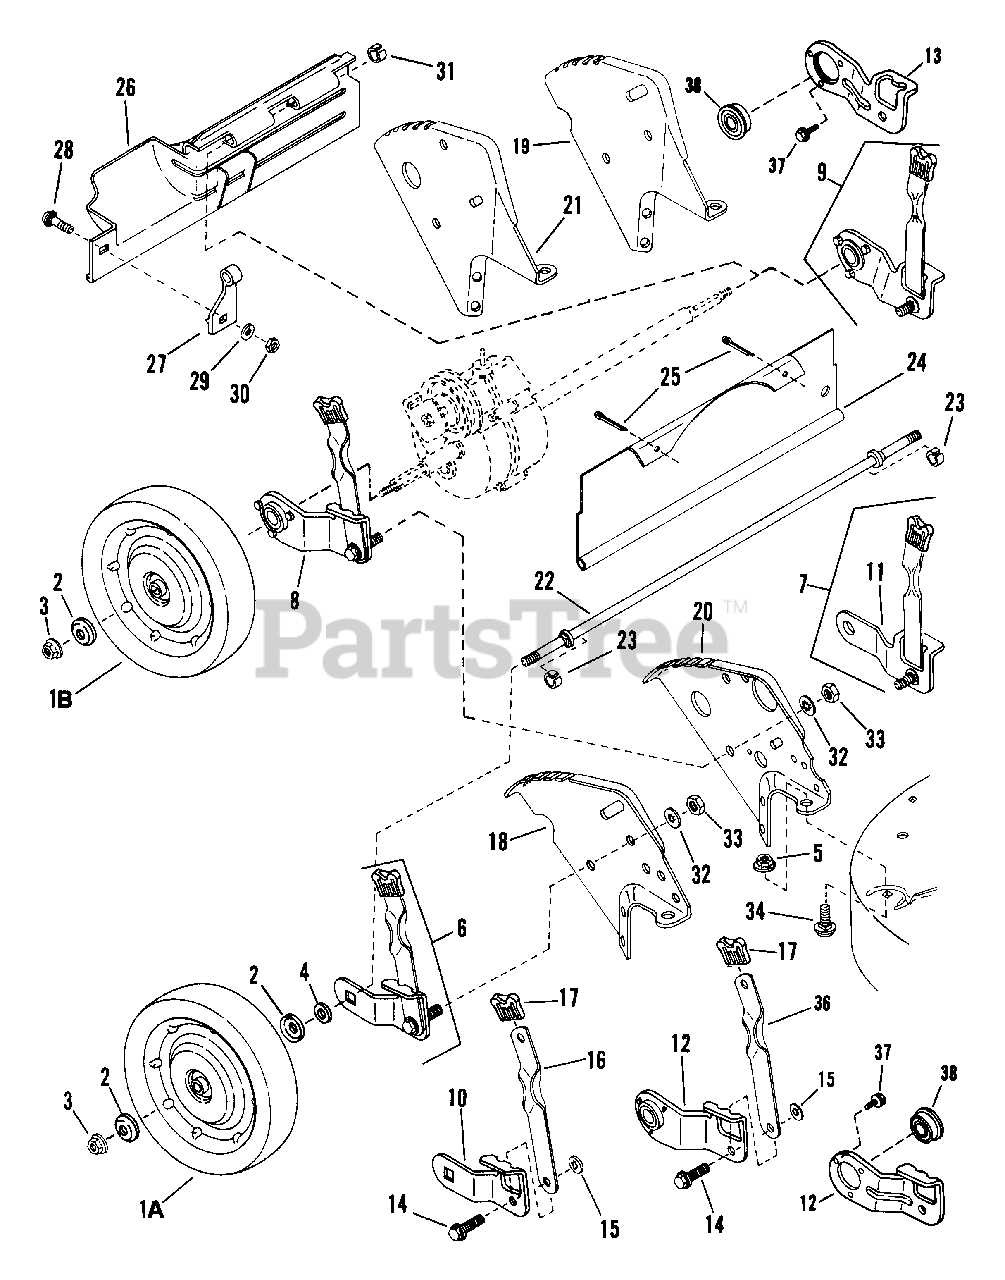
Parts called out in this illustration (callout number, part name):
1A	WHEEL, 9 x 2.00 Steel Rim
1B	WHEEL, 9 x 2.00 Steel Rim
2	HUB-CAP
3	NUT, 7/16-20 Hex Center Lock
4	WASHER, Steel
5	NUT, 5/16-18 Hex Flang Lock
6	WHEEL ARM ASSEMBLY (Front Left & Rear Right) Square opening
7	WHEELARM ASSEMBLY (Front Right & Rear Left) Round opening
8	WHEEL ARM ASSEMBLY (Rear Right "P" Models)
9	WHEEL ARM ASSEMBLY (Rear Left "P" Models)
10	ARM (Square Axle End)
11	ARM (Round Axle End)
12	ARM, Wheel, Rear Right "P" Models
13	ARM, Wheel, Rear Left "P" Models
14	BOLT, 5/16-18 x 1 Shoulder
15	RETAINER, 5/16 Bolt
16	LATCH, Height Adjusting
17	GRIP, Latch
18	BRACKET, Right Rear Wheel
19	BRACKET, Left Rear Wheel
20	BRACKET, Right Rear Wheel
21	BRACKET, Left Rear Wheel
22	AXLE, (Rear on Push Models also front on all)
23	RING
24	GUARD, Rear Foot
25	COTTER PIN, 1/8 x 1-1/2
26	GUARD, Rear Foot
27	SUPPORT, Foot Guard
28	BOLT, 1/4-20 x 1/2 Short Neck Carriage Gr.5
29	WASHER, 1/4 Int. Tooth Lock
30	NUT, 1/4-20 Hex
31	RING
32	WASHER, 5/16 Int. Tooth Lock
33	NUT, 5/16-18 Hex
34	BOLT, 5/16-18 x 1/2 Short Neck Carriage
36	LATCH, Height Adjusting
37	SCREW, #10-32 x 3/8 Self-Tapping
38	BEARING
